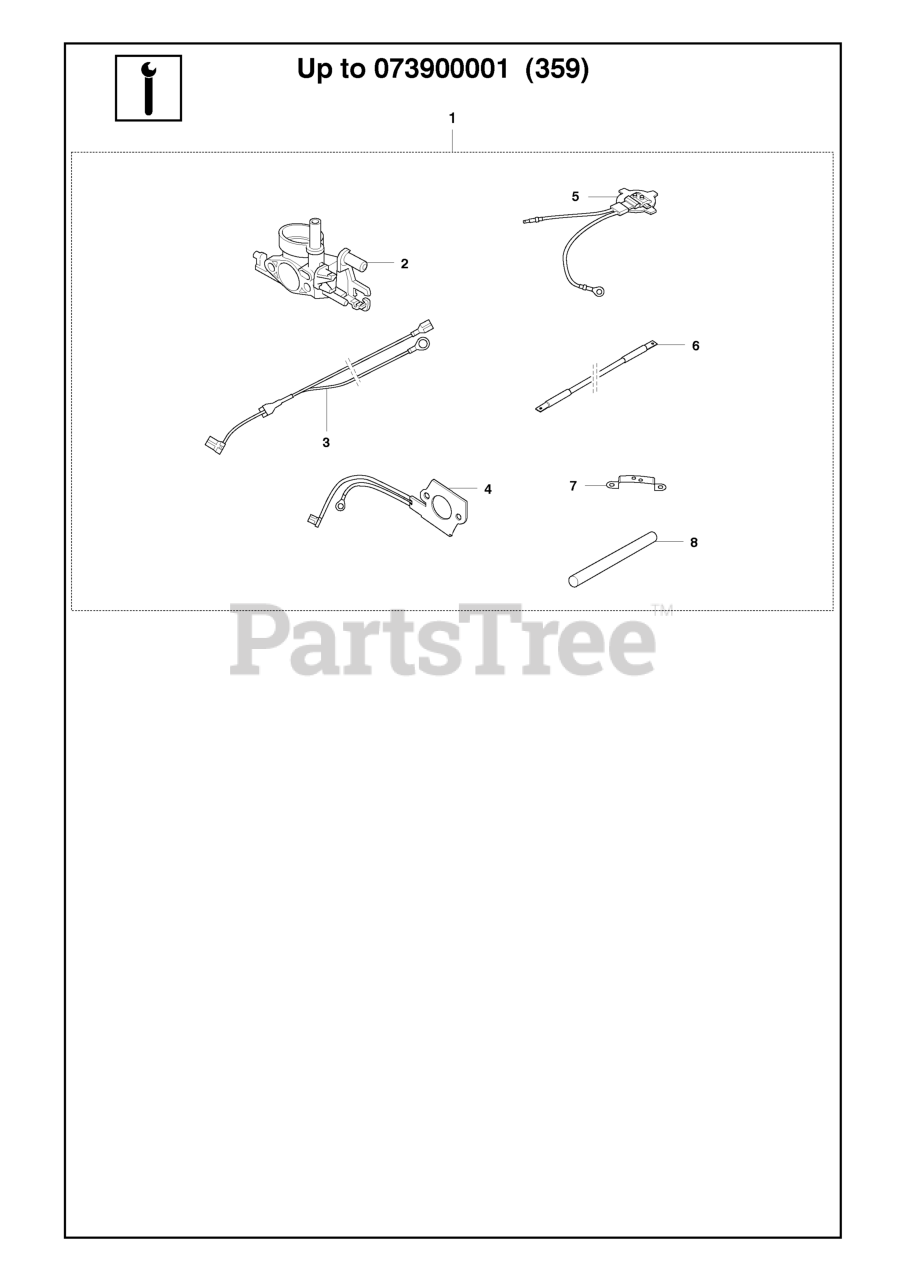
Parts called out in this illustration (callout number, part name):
2	FILTER HOLDER
3	WIRING ASSY
4	HEATING PLATE
5	THERMOSTAT ASSY
6	WIRING ASSY
8	CABLE COVER
